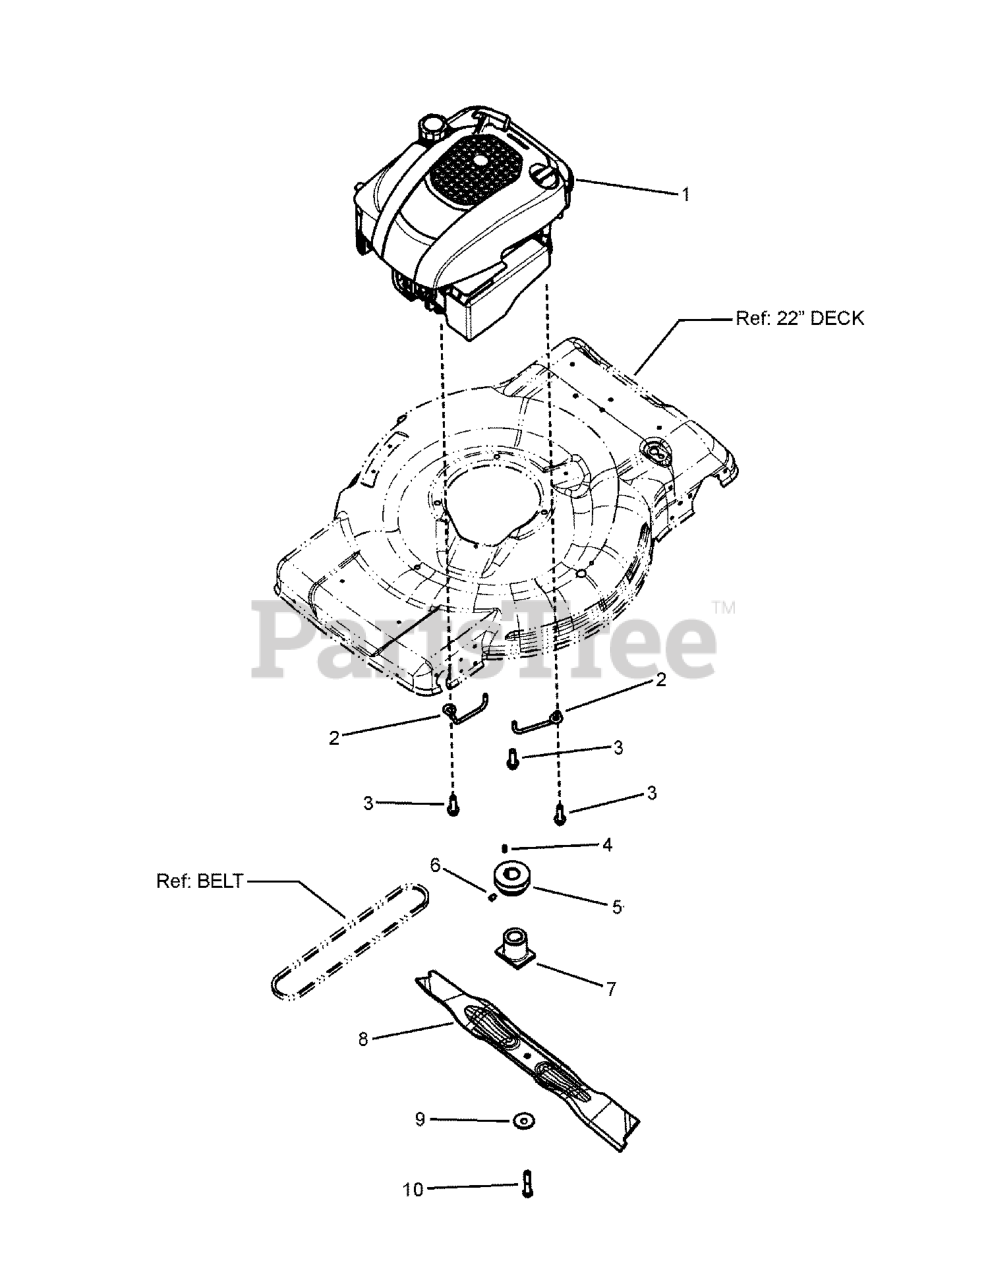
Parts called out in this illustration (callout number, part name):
1	ENGINE, W-14, 875 SERIES W/ ES, DEERE, FC
2	BELT GUIDE, ENGINE, FWD
3	HWST, 3/8-16 X 1.25
4	KEY, #HP-506 HI-PRO
5	PULLEY, ENGINE
6	HRSS, 5/16-18X1/2
7	HUB, BLADE, 21" WBM, RD, 2 POSITION
8	BLADE, 22", WAVE, DEERE, STEEL DECK
9	WASHER, CONE
10	HHCS, 3/8-24X2 GR5
